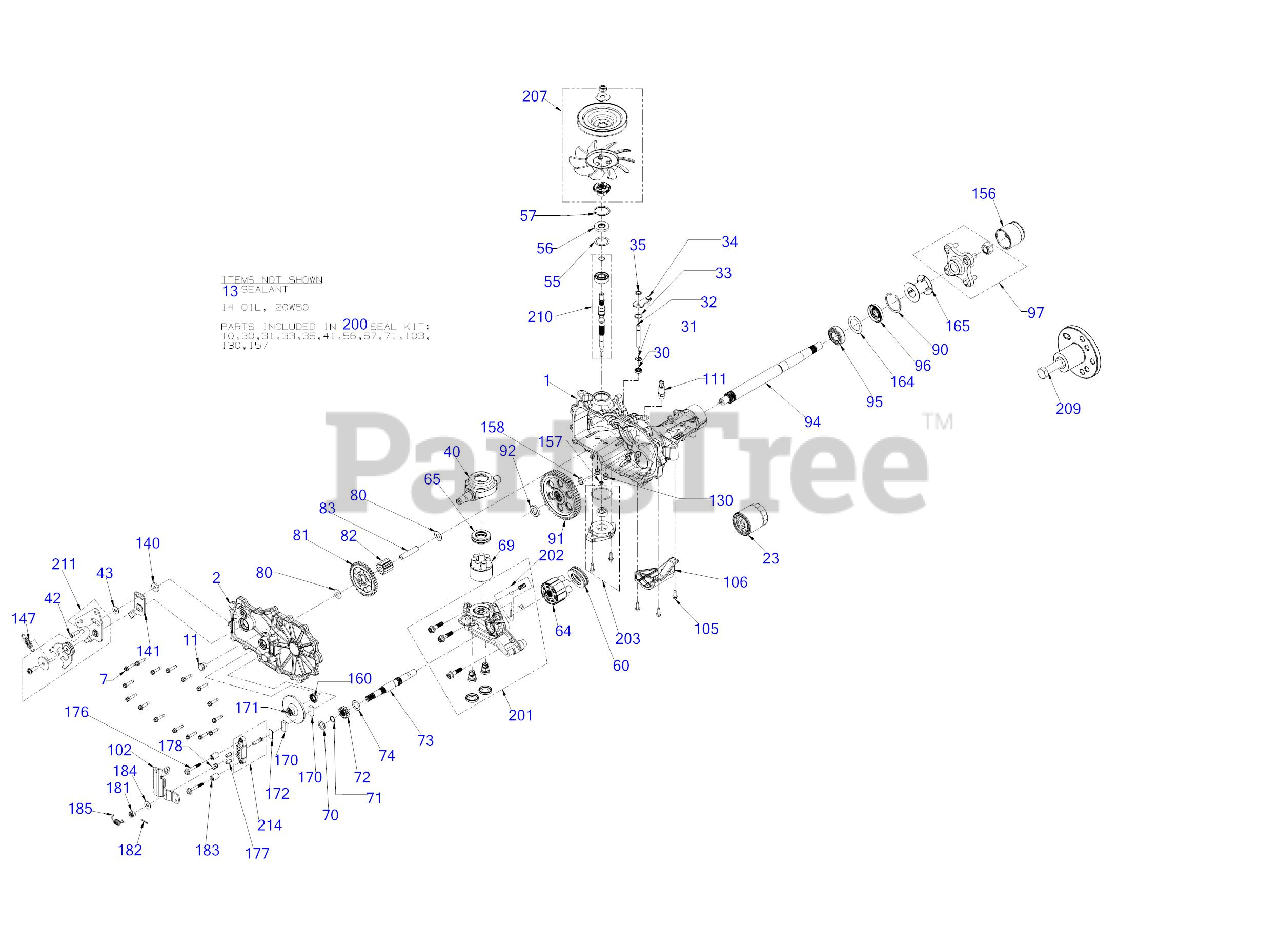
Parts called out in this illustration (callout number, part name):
1	HOUSING KIT (RH)
2	CONTROL COVER KIT (RH)
7	SCREW-WASHER HEAD
11	VENT PLUG
13	SEALANT-HOUSING
23	FILTER-OIL
30	SEAL-LIP .375
31	RETAINING RING
32	BYPASS RODS
33	RETAINING RING
34	ARM-BYPASS
35	RETAINING RING
40	SWASHPLATE-TRUNNION
42	SCREWS KIT-RTN
43	FLAT WASHER
55	WASHER 1.23X1.56X
57	RETAINING RING
60	THRUST BEARING
64	BLOCK ASSEMBLY-CYLINDER
65	THRUST BEARING
69	BLOCK KIT-CYLINDER
70	FLAT WASHER
71	RETAINING RING
72	GEAR - 13 TOOTH STEEL
73	MOTOR SHAFT
74	MOTOR SHAFT WASHER
81	GEAR - 46 TOOTH
82	GEAR-11 T
83	PIN-JACKSHAFT
90	RETAINING RING
91	GEAR - 54 TOOTH
92	SPACER .75X1.32X.257
94	AXLE SHAFT
95	BALL BEARING
97	HUB KIT-4 BOLT
102	ARM-BRAKE
106	GUARD-FILTER (RH)
111	FITTING-STEERINGT BARB
130	TUBE-CHARGE TRIPLE O-RING
140	SPACER .32 x 1.005 x .179
141	ARM-NEUTRAL (RH)
147	EXTENSION SPRING
157	KIT-GEROTOR SEAL
158	MAGNET-RING
165	TUBE-AXLE 2.03
170	BRAKE PUCK
171	ROTOR-BRAKE
172	PLATE-PUCK
176	BOLT-SPECIAL FLANG
177	ACTUATING PIN
178	BRAKE SPRING
181	NU-HEX INS JAM
182	COTTER PIN-3/32
183	SPACER-TORSION SPG
184	FLAT WASHER
185	BRAKE SPRING
200	KIT - SEAL
201	CENTER SECTION KIT (RH)
202	KIT-CHARGE RELIEF
203	CHARGE KIT
207	FAN & PULLEY KIT
209	PULLER KIT-HUB
210	INPUT SHAFT KIT
211	RETURN KIT-NEUTRAL
214	BRAKE YOKE ASSEMBLY
